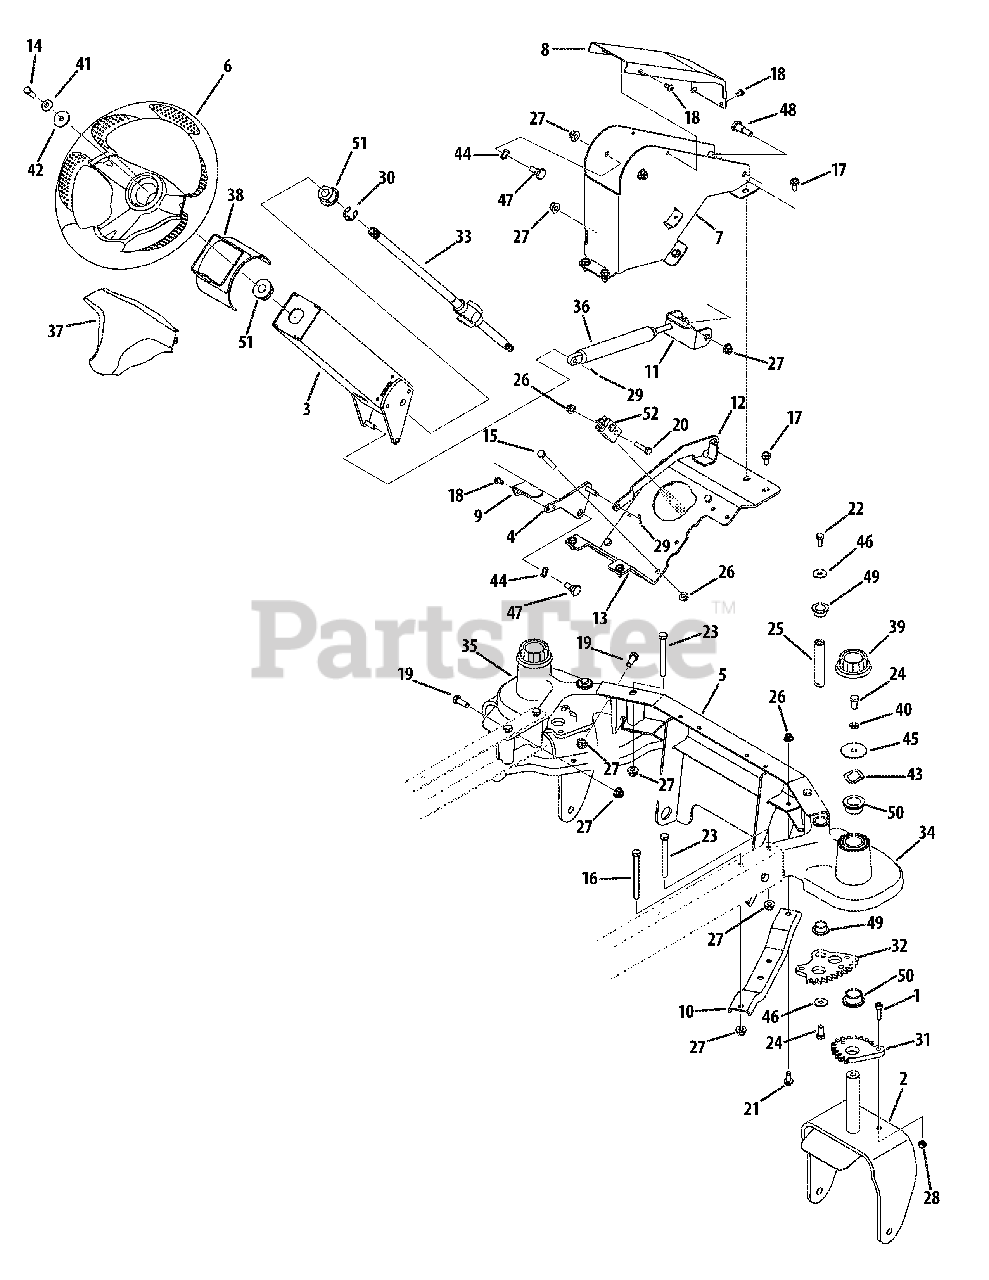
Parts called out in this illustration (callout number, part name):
1	Socket Head Screw, 5.16-18 x 1.00
2	Caster Bracket Assembly
3	Upper Steering Column Assembly
4	Tilt Release Pedal Assembly
5	Front Bumper Frame Assembly
6	Steering Wheel Assembly
7	Lower Steering Wheel Column
8	Lower Column Cover
9	Tilt Steering Pedal
10	Front Fram Brace
11	Damper Pivot Lower Bracket
12	Tilt Action Lever
13	Stering Mount Box Plate
14	Hex Screw, 5.16-18 x 1.00
15	Hex Screw, 5.16-18 x 2.25
16	Hex Screw, 3.8-16 x 4.00
17	Hex Washer Screw, 5.16-18 x .750
18	Screw, 1.4-20 x .5
19	Hex Screw, 3.8-16 x 1.00
20	Hex Screw, 5.16-18 x 1.25
21	Hex Washer Screw, 5.16-18 x 750
22	Hex Screw, 5.16-18 x .75
23	Hex Screw, 3.8-16 x 3.50
24	Hex Screw, 3.8-16 x .750
25	Pivot Gear Steering Shaft
26	Flange Lock Nut, 5.16-18
27	Flange Lock Nut, 3/8-16
28	Hex Lock Nut, 5.16-18
29	Cotter Pin, 3.32 x .750
30	E-Ring, .750
31	13-Tooth Variable Spur Gear
32	12-Tooth Variable Gear
33	Steering Shaft
34	RH Flange Bearing Caster Pivot Axle
35	LH Flange Bearing Caster Pivot Axle
36	Locking Damper Cylinder, 80MM
37	Steering Wheel Cover
38	Column Cover
40	Lock Washer, 3.8
41	Bell Washer, .340 x .872 x .060
42	Flat Washer, .330 x 1.25 x .120
43	Wave Washer, 1.5 x 1.0 x .029
44	Wave Washer, .510 x.750 x .017
45	Flat Washer, .406 x 1.92 x .060
46	Flat Washer, .344 x 1.00 x .063
47	Shoulder Bolt, 3.8-16 x .496 x .336
48	Shoulder Screw, 3.8-16 x .50 x .66
49	Flange Bearing, 3.4 x .52
50	Flange Bearing, 1.0 x 1.25 x 1.62
51	Flange Bearing, .630 x 1.50
52	Steering Shaft Block
